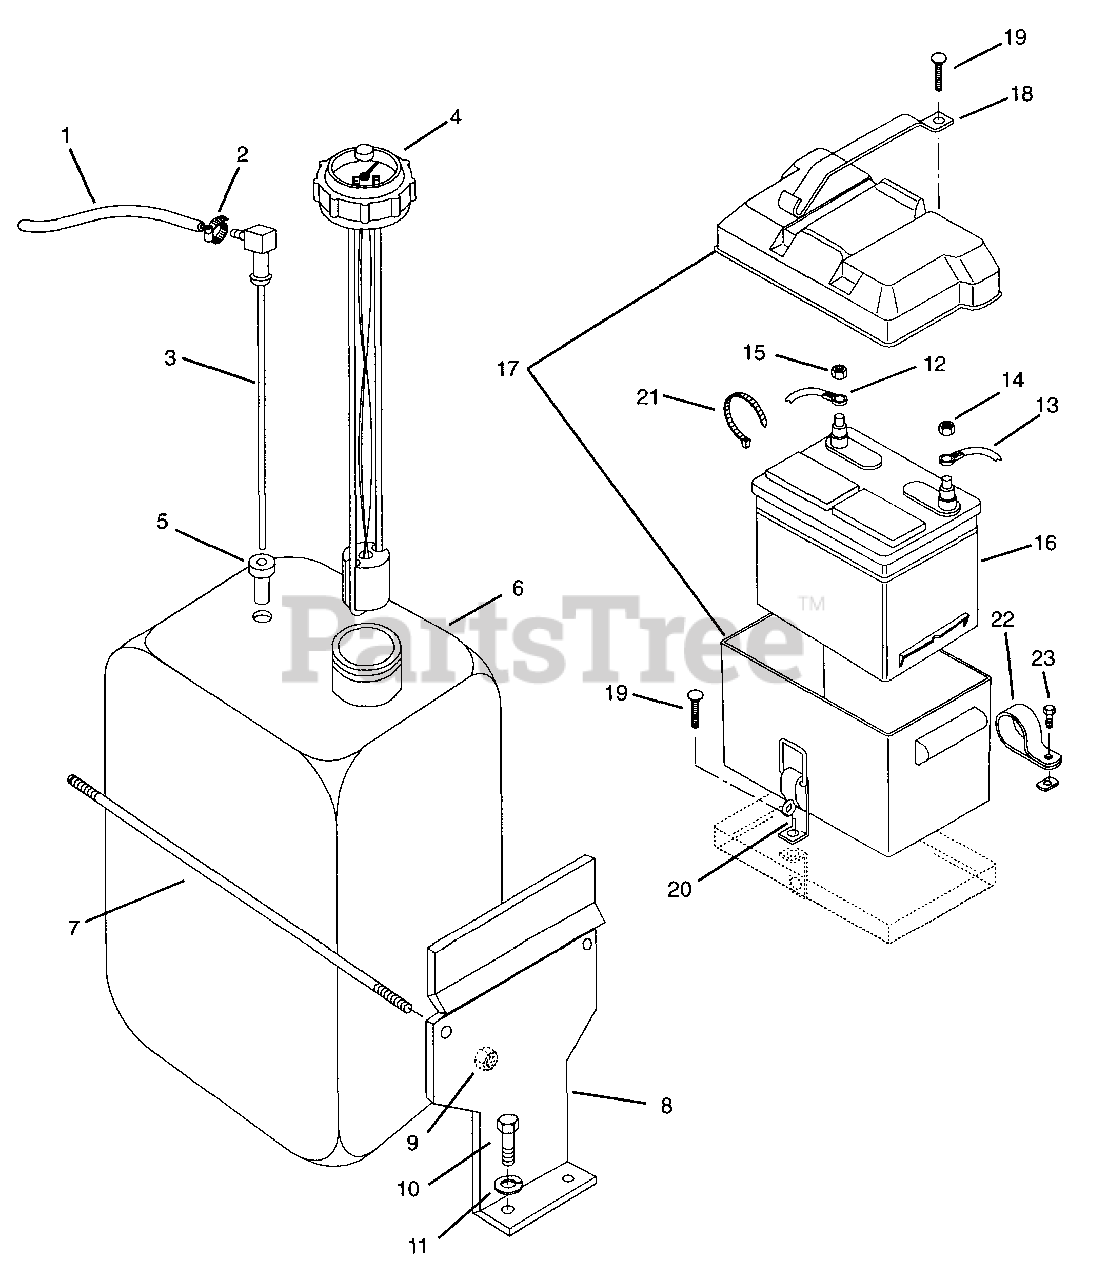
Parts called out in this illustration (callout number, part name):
1	Gas Line - Bulk 1/4 IN. Inner Diameter
2	Hose Clamp
3	Fitting, Tank
4	Gauge, Fuel
6	Tank, Fuel
7	Rod, Tank
8	Weldment, Tank Bracket
9	Nut-Locking-Center .31-18
10	Bolt-Hex .31-18 x .50 Grade 5
11	Washer-Locking .31 x .078
12	Negative Battery Cable
13	Positive Battery Cable
14	Nut-Hex .31-18
15	Nut-Hex .38-16
16	Battery, Marine Type
17	Battery Box
18	Strap-Battery Hold-Down
19	Bolt-Round Head Square Neck .31-18 x 1.75 Grade 5
20	Latch Assembly - Battery Hold-Down
21	Tie Wrap
22	Clamp-Steel 1.0
23	Bolt-Hex .38-16 x .75 Grade 5
